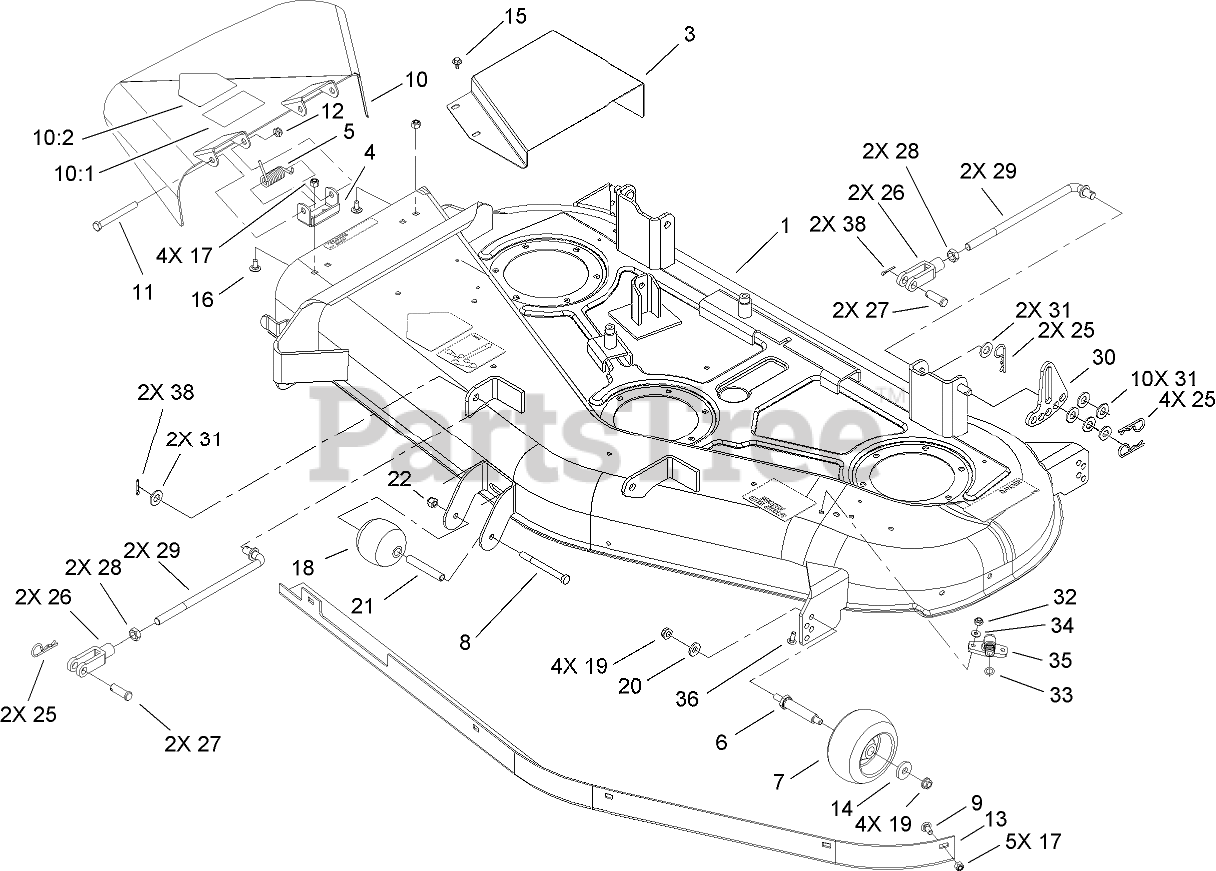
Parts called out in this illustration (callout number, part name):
1	52 INCH DECK ASM
3	COVER-BELT, RH
4	BRACKET-PIVOT
5	SPRING
6	SPACER
7	ROLLER-SCALP, ANTI
8	SCREW-HH
9	SCREW-CARR
10	DEFLECTOR ASM
10:1	DECAL-DANGER
10:2	DECAL-DANGER
11	SCREW-HH
12	NUT-HEX
14	WASHER
15	SCREW-HHFTF
16	SCREW-CARR
17	NUT-LOCK, NI
18	ROLLER
19	NUT-HHF, WHIZ
20	WASHER-BELLEVILLE
21	TUBE-SPACER, WHEEL
22	NUT-LOCK, NI
25	PIN-COTTER
26	CLEVIS
27	PIN-CLEVIS
28	NUT-JAM
29	ROD-TRUNION
30	LINK-HOC, ADJUSTING
31	WASHER-FLAT
32	NUT-LOCK, NI
33	O-RING
34	WASHER-FLAT
35	FITTING-WASHOUT
36	BOLT-CARR
38	PIN-COTTER
